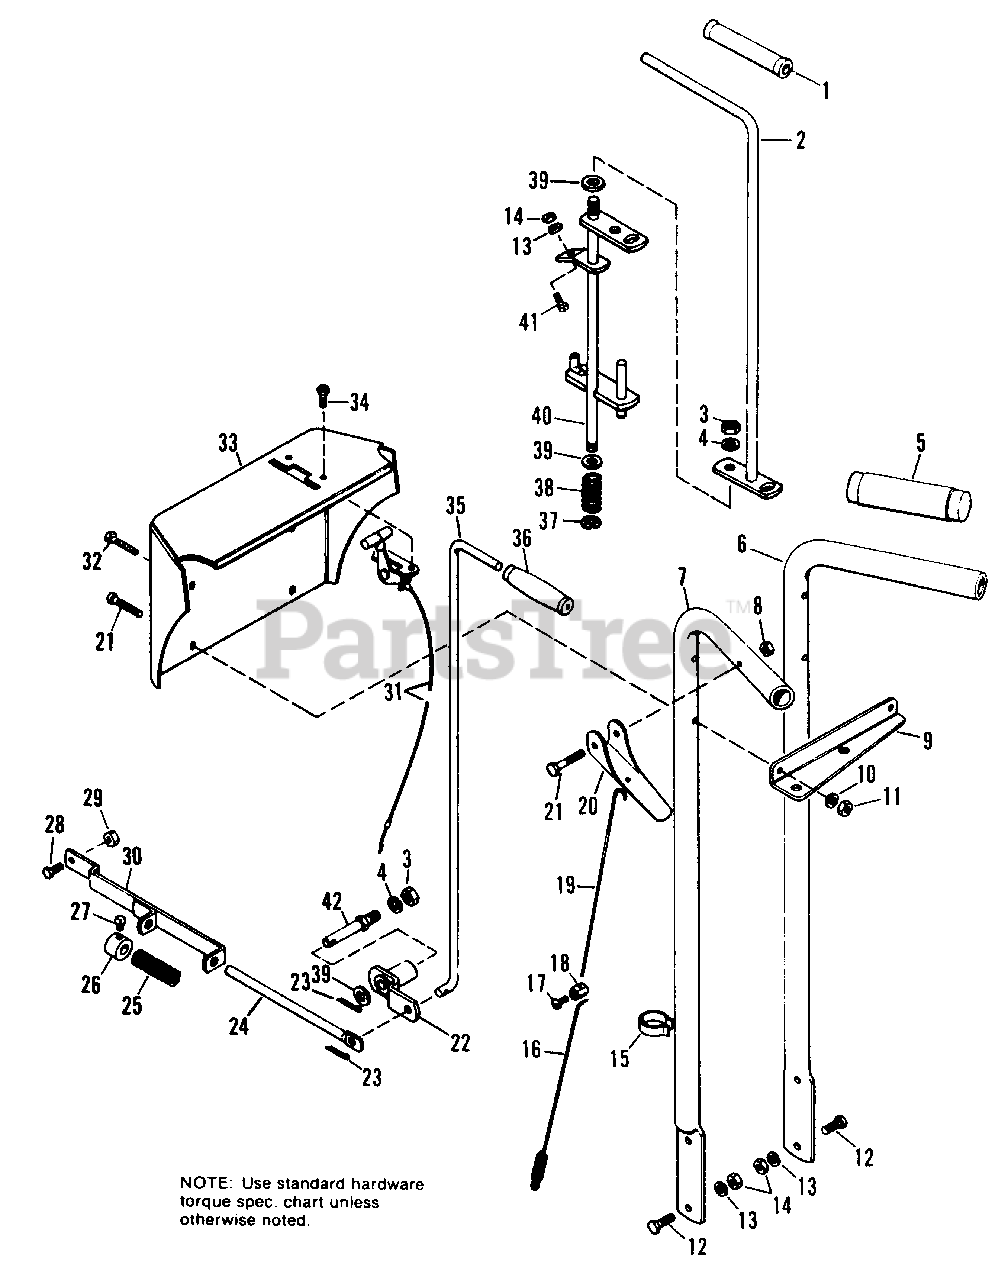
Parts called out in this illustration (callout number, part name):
1	GRIP, Handle
2	ROD ASSY., Shift, Upper
3	NUT, Hex, Full, 7/16-14
4	LOCKWASHER, 7/16
6	HANDLE, R.H.
7	HANDLE, L.H.
8	LOCKNUT, Hex, Full, 1/4-20
9	GUIDE, Rod
10	LOCKWASHER, 1/4
11	NUT, Hex, Full, 1/4-20
12	CAPSCREW, Hex, 5/16-18 x 7/8
13	LOCKWASHER, 5/16
14	NUT, Hex, Full, 5/16-18
15	CLIP, Cable
16	SPRING ASSY.
17	SCREW, Rd. Hd., #10-24 x 3/8
18	CLAMP, Wire
19	EXTENSION, Spring
20	GRIP, Clutch
21	CAPSCREW, Hex, 1/4-20 x 1-1/2
22	ARM ASSY., Pivot
23	PIN, Cotter, 1/8 x 3/4
24	ROD, Clutch
26	SET COLLAR
27	SETSCREW, Sq. Hd., 1/4-20 x 3/8
28	CAPSCREW, Hex, 5/16-18 x 5/8
29	LOCKNUT, Hex, 5/16-18
30	GUIDE, ASSY., Rod
31	CONTROL ASSY.
32	CAPSCREW, Hex, 1/4-20 x 1-3/4
33	HOUSING ASSY., Control
34	SCREW, Hex Hd., Self Tapping, 1/4 x 20 x 1/2
35	ROD, Idler
37	RING, Retaining
39	WASHER, Plain, 3/8
40	ROD ASSY., Shift Lower
41	CAPSCREW, Hex, 5/16-18 x 7/8
